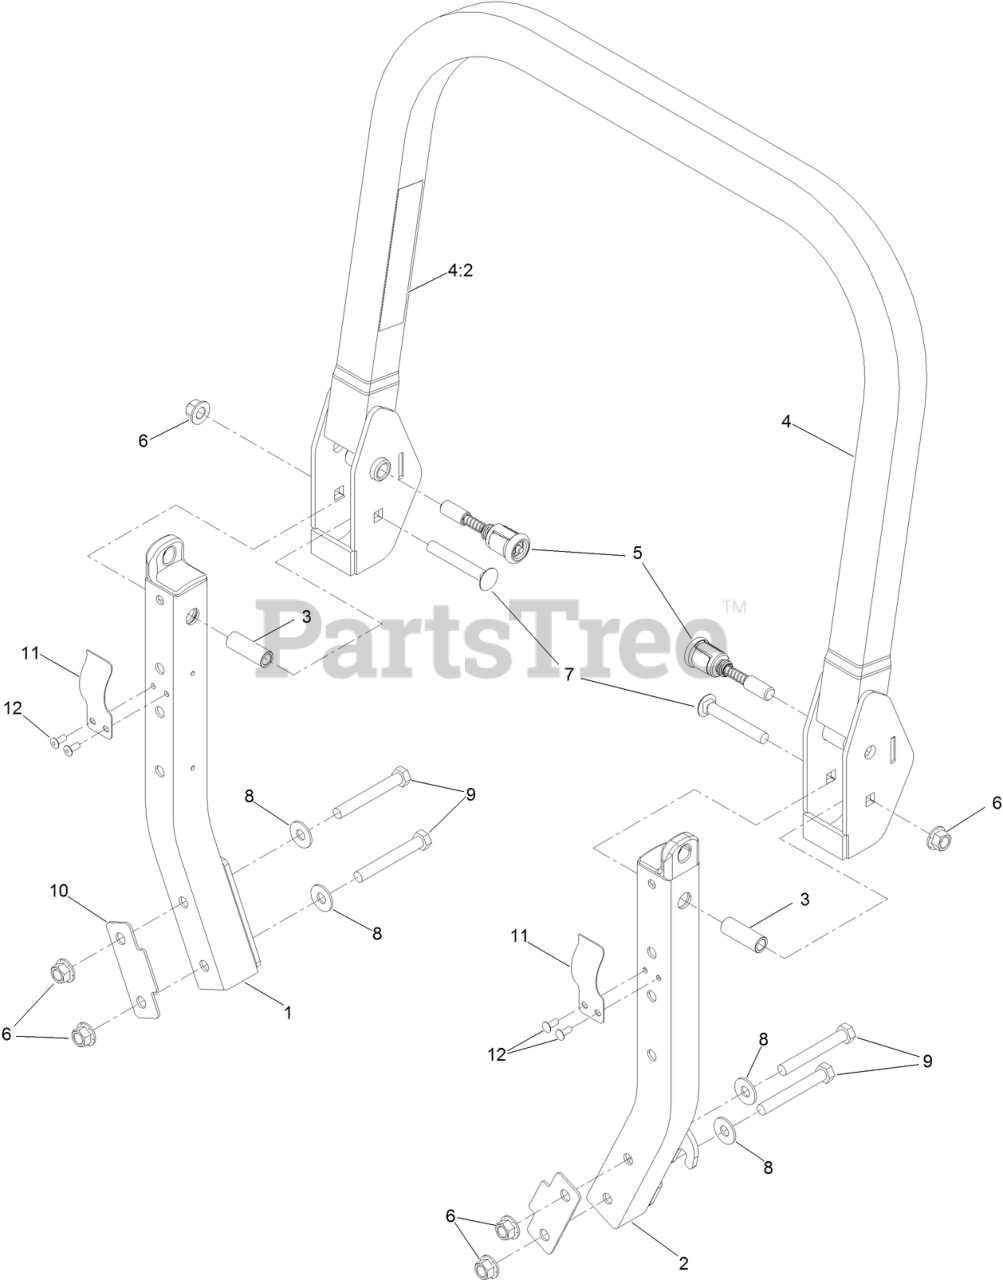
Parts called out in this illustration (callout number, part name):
1	LOWER-ROPS, RH
2	LOWER-ROPS, LH
3	SPACER
4	ROPS UPPER ASM
4:2	DECAL-WARNING
5	PIN-SPRING
6	NUT-LOCK
7	SCREW-CARR
8	WASHER-SPRING
9	SCREW-HH
10	SPACER
11	SPRING-LEAF
12	RIVET-BLIND
